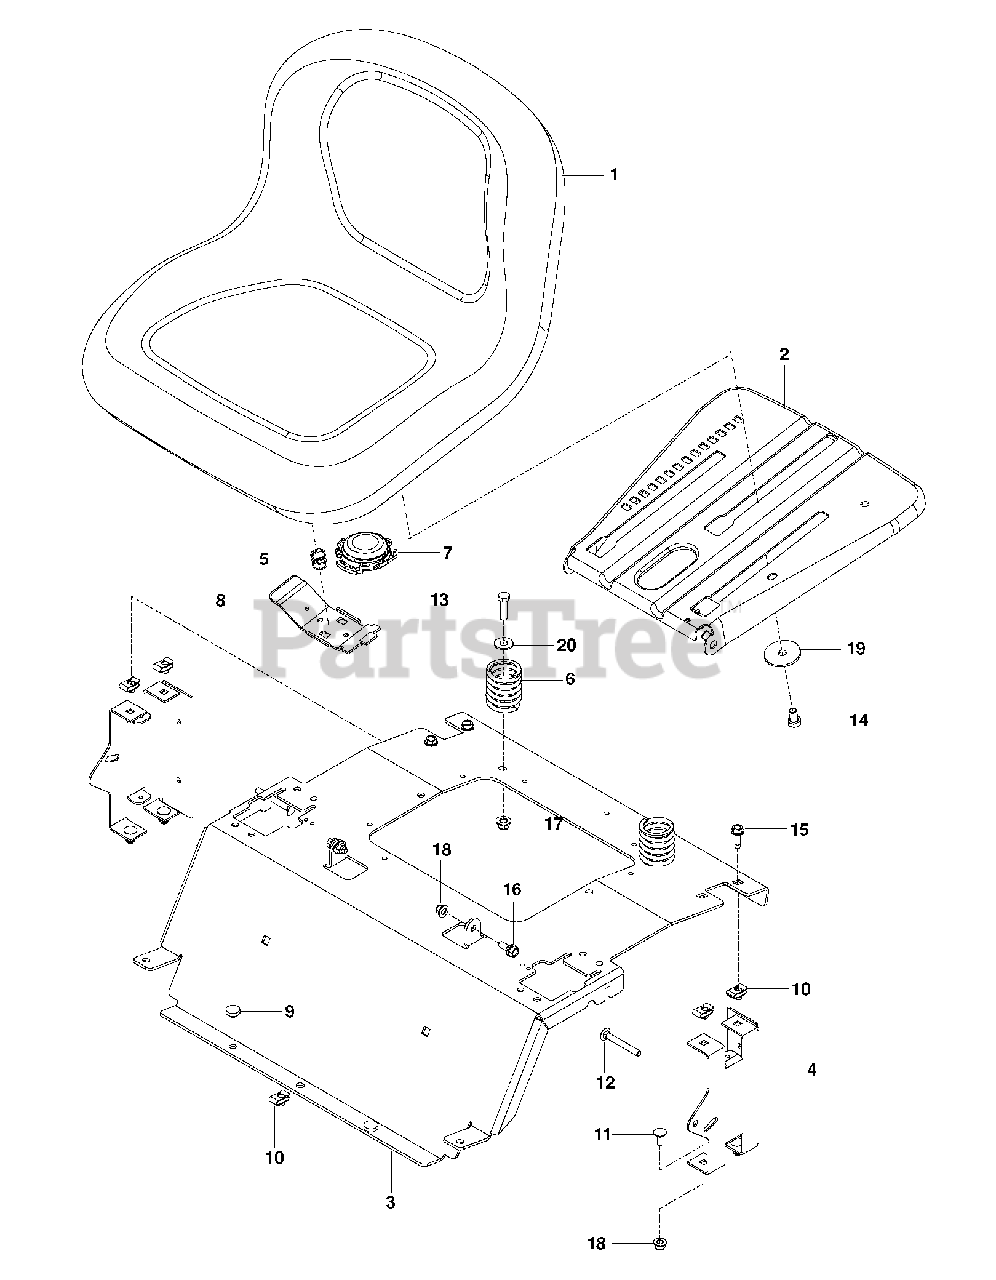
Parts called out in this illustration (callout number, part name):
1	SEAT.TH150.MS498.GRY.HUSQ.TEX
2	PAN.ASM.SEAT.3PT
3	SUPPORT SEAT ORANGE
4	SUPPORT, REAR SEAT, BLACK
5	SPRING.LATCH.SEAT.TEX
6	SPRING COMPRESSION
7	SWITCH.SEAT.OPC.DELTA.W/3LB.HL
8	HANDLE.SLIDE.SEAT.TEX.BLACK
9	GROMMET, BUMPER
10	U-CLIP 5/16-18 NUT RETAINER
11	BOLT 5/16-18 X3/4 ZN/YEL GR 5
12	RHSNB 5/16-18 X 2-1/2 GR5 ZD
13	BOLT
15	SCREW
16	BOLT, SHOULDER
17	NUT 3/8-16 HEX FLG NYLOC ZD
18	5/16-18 NYLOC FLANGE NUT
19	WASHER, 3/8 SPEC
20	WASHER 3/8 FLAT
